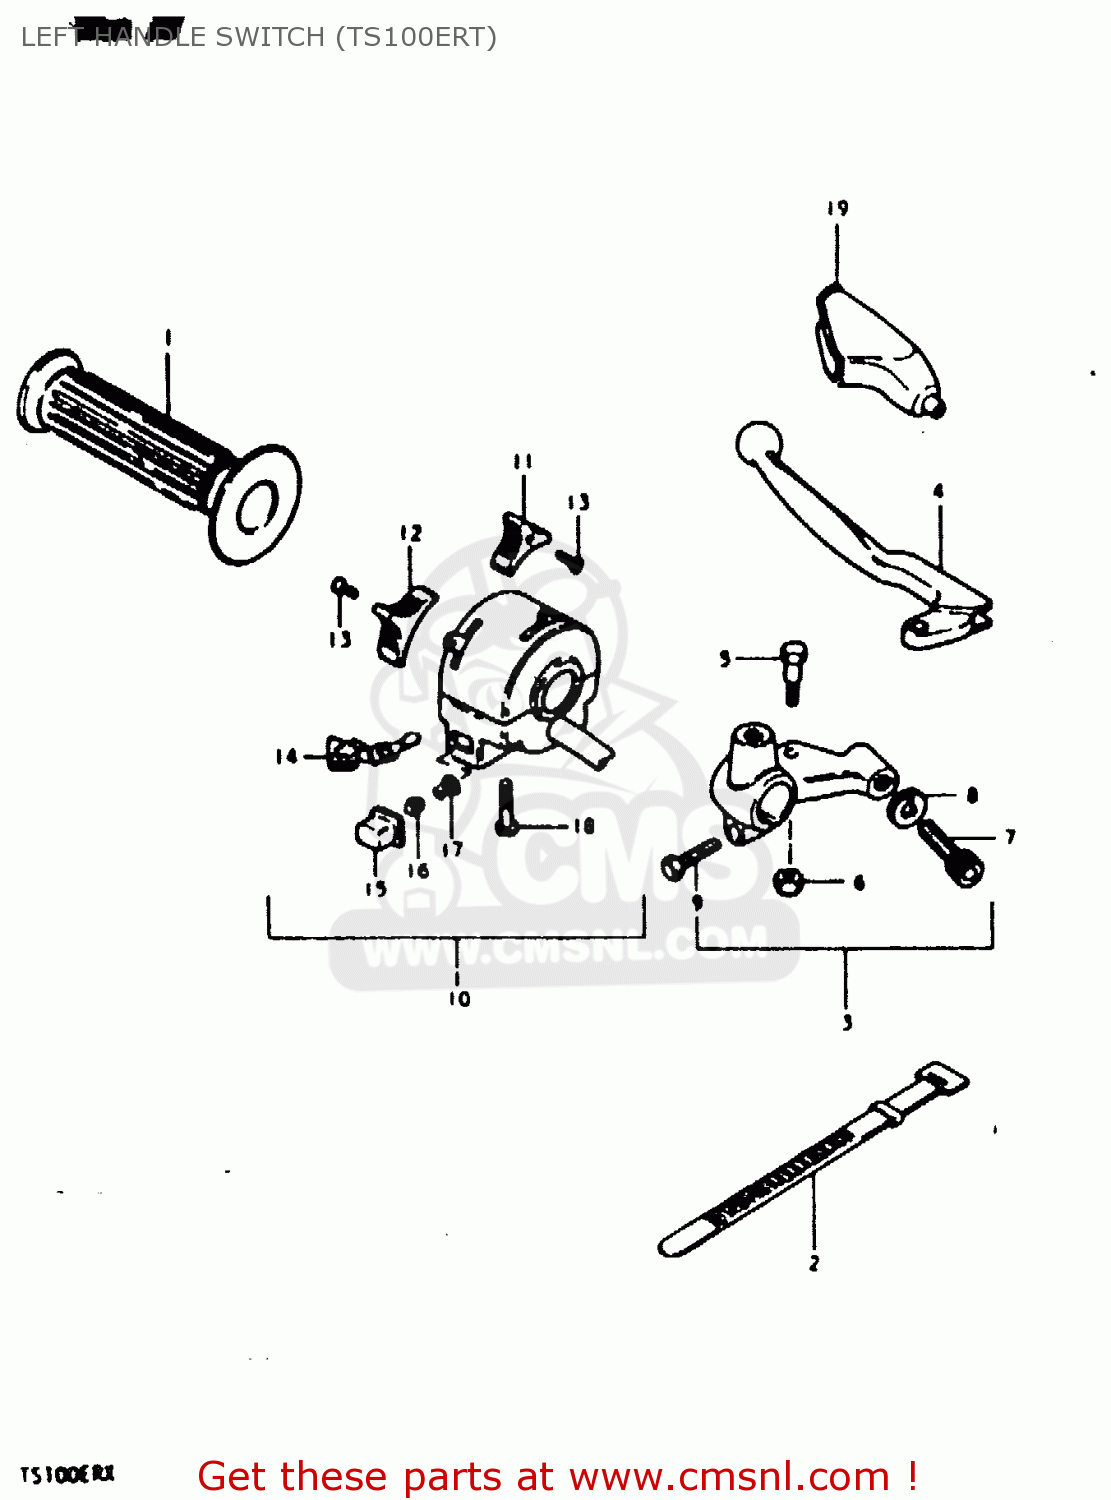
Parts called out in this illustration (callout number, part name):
1	GRIP,L
2	CLAMP(L:120)
3	LEVER ASSY,CLUTCH
4	LEVER,CLUTCH
5	BOLT,LEVER
6	NUT 6MM
7	ADJUSTER,CABLE
8	NUT,CABLE ADJUSTER
9	BOLT
10	SWITCH ASSY,HANDLE,L
11	KNOB,LIGHTING SWITCH
12	KNOB,DIMMER SWITCH
13	SCREW
14	KNOB,TURNSIGNAL
15	BUTTON,HORN
16	CONTACT
17	SPRING
18	SCREW
19	COVER,CLUTCH LEVER
